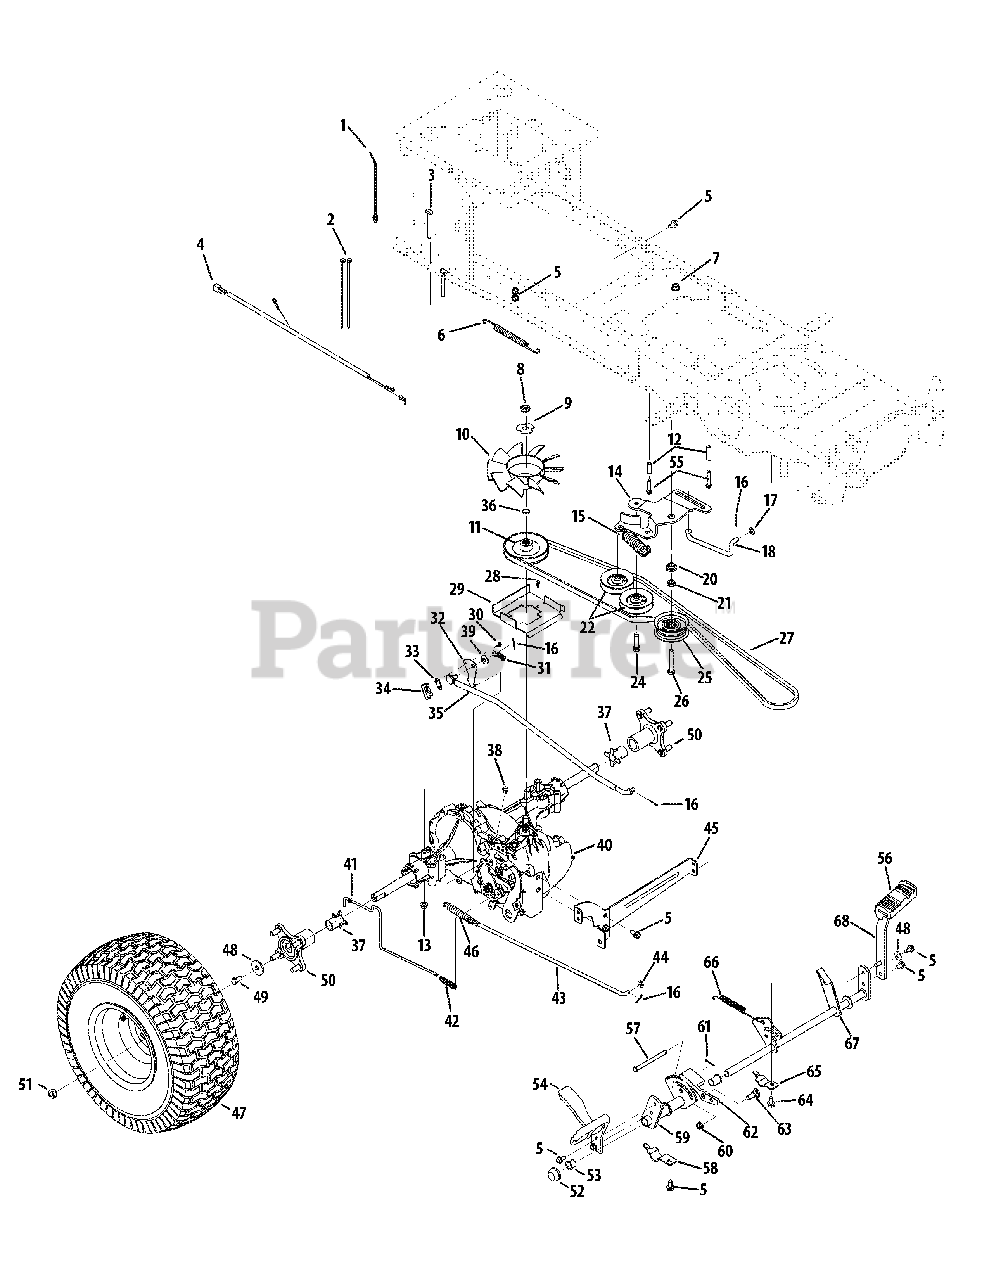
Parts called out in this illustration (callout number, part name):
1	Cable Tie, 7.5
2	Cable Tie, 3/16 x .05 x 7.4
3	Hex Bolt 5/16-18 x 2.75
4	Jumper Harness
5	S-Tapp Screw 5/16-18 x .75
6	Extension Spring .50 dia. x 12.6
7	Flange Locknut 3/8-16 Gr. F
8	Jam Locknut 1/2-10
12	Spacer, .260 x .372 x 1.420
13	Flange Locknut 5/16-18 Gr. F, Nylon
14	Idler Bracket
15	Extension Spring .59 x 4.0
16	Cotter Pin 3/32 dia x 1.00 Lg.
17	Flat Washer .330 x .630 x .0635
18	Pedal Transmission Bypass Rod
20	Shoulder Spacer 1.375 x .38 x .183
21	Hex Jam Nut 7/16-20
24	Hex L-Wash HD Screw 3/8-16 x 1.5
25	Idler Pulley, Flat 2.75 OD
26	Hex Bolt 3/8-16 x 2.25" Lg.
28	Truss Mach B-Tapp Screw #10 X .50
29	Belt Disengage Support Bracket
30	Hex Washer Screw #8-18 x .50
31	Extension Spring 3/8 x 1.44
32	Switch Actuator Bracket
33	Insulator Nut Plate
34	Short Spring Switch
35	Hydro Control Rod
37	Sleeve 0.765 x 2.41
38	Hex Wash HD Tapp Screw 1/4-20 x .375
39	Flat Washer .406 ID x .812 OD x .134
40	Hydro Transmission
41	Hydro By pass Rod
42	Extension Spring .47 OD x 2.03 Lg.
44	Flat Washer .312 ID x .75 OD
45	Hydro Mount Bracket
46	Extension Spring .59 x 4.0
47	Wheel Ass'y Comp. 22 x 9.5 x 12
48	Cupped Washer .345 ID x .88 OD x .060
49	Hex L-Bolt 5/16-24 x .75 Gr. 5
50	Wheel Hub Ass'y
52	Push Cap 5/8" Dia Rod
53	Nyliner Flanged Brg.
55	Hex Washer Hd. TT Screw 1/4-20 x 1.625
56	Brake Pedal Pad
57	Clevis Pin 5/16 x 3.985
58	Transmission Rod Support Strap
59	Hydro Pedal Brkt. Assembly
60	Flange Lock-Nut 3/8-16 Gr. F Nylon
61	Bow-Tie Cotter Pin
63	Shoulder Screw .500 x .25
64	Self-tapping Screw 5/16-18 x .625
65	Brake Shaft Support Strap
66	Extension Spring .63 x 4.95
67	Brake Control Assembly
68	Brake Pedal Bracket
